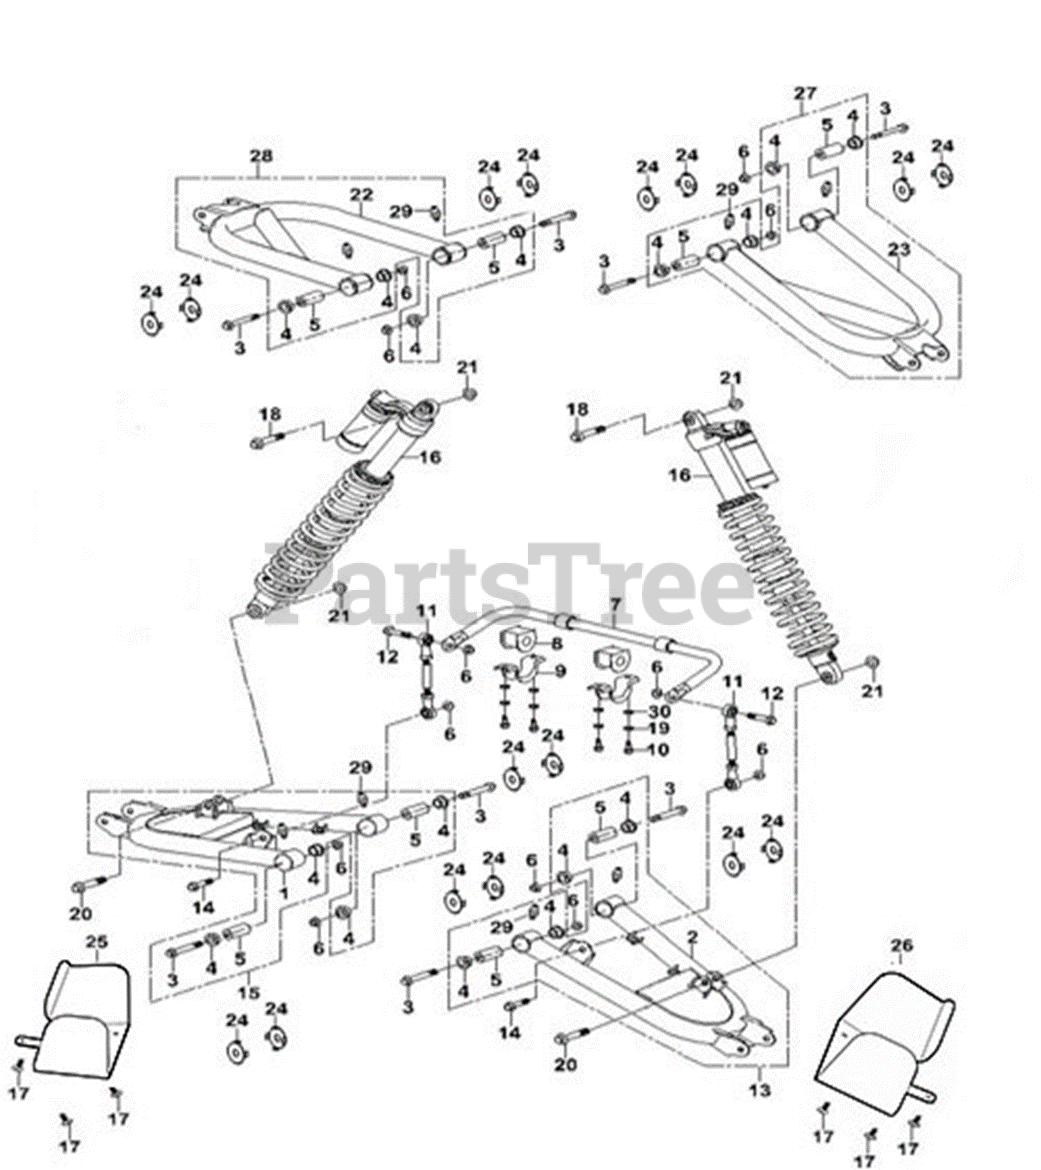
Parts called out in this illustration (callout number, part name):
1	Arm Welding Kit(Rear Right Lower)
2	Arm Welding Kit(Rear Left Lower)
3	HEX HEAD FLANGE BOLT M10X1.25-80
4	SHOULDER SPACER
5	BUSHING 10.3X23X49.4
6	LOCK NUT M10X1.25
7	STABILIZER BAR (REAR)
8	BUSHING - RUBBER U-TYPE
9	PRESS BLOCK REAR ANTI-ROLL BAR
10	HEX FLANGE BOLT M10X1.25X20
11	ROD BALL KIT - REAR
12	HEX FLANGE BOLT M10X1.25X50
13	LOWER A-ARM ASSEMBLY (REAR LH)
14	HEX FLANGE BOLT M10X1.25X45
15	LOWER A-ARM ASSEMBLY (REAR RH)
16	REAR SHOCK ABSORBER
17	HEXAGON FLANGE BOLT M6X16
18	HEX HEAD BOLT M12X1.25-70
19	SPRING WASHER
20	HEX HEAD BOLT M12X1.25-65
21	LOCK NUT M12X1.25
22	Arm Welding Kit(Rear Right Upper)
23	Arm Welding Kit(Rear Left Upper)
24	BUSHING CAP I
25	CV SHIELD (REAR) (RH)
26	CV SHIELD-REAR (LH)
27	UPPER ARM ASSEMBLY (REAR LH )
28	UPPER ARM ASSEMBLY (REAR RH)
29	SWING ARM NOZZLE
